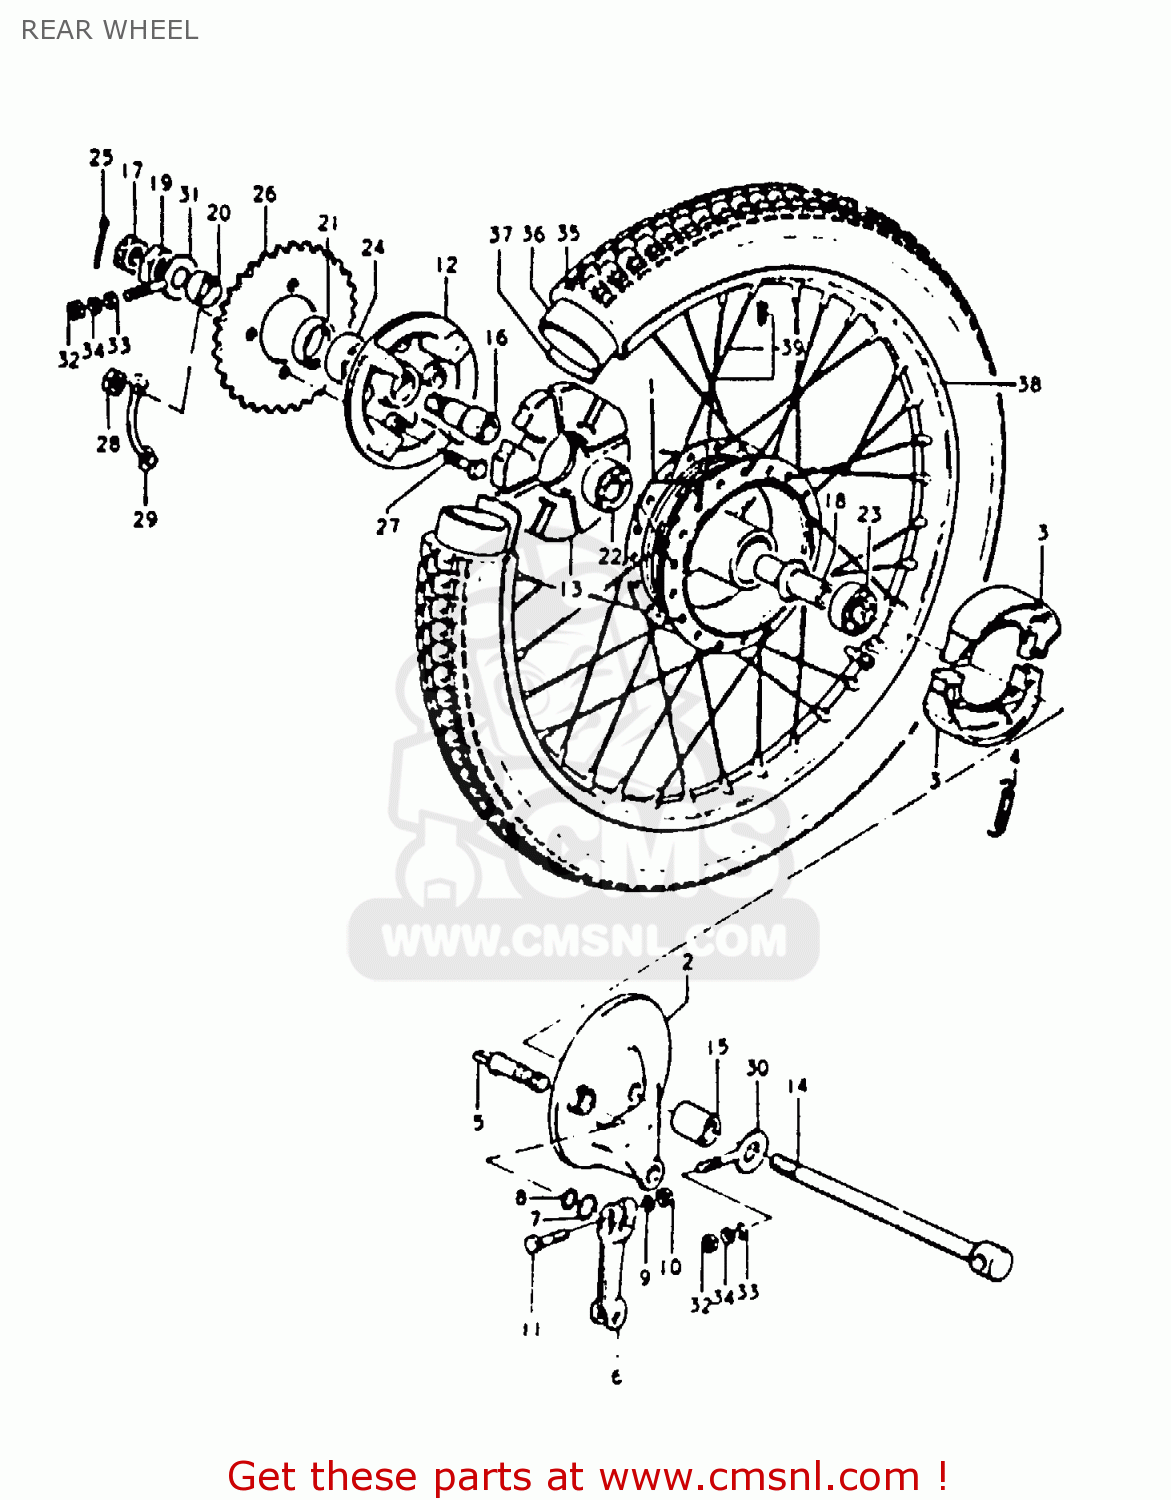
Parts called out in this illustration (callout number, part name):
1	HUB,REAR WHEEL
2	PANEL,REAR HUB
3	SHOE,BRAKE
4	SPRING(L:34)
5	CAM,FR BRAKE
6	LEVER,REAR BRAKE CAM
7	WASHER(12.5X20X1)
8	O RING(D:2.5,ID:11.4)
9	WASHER
10	NUT
11	BOLT
12	DRUM,REAR SPROCKET MOUNT
13	CUSHION,REAR DRUM
14	AXLE,REAR
15	SPACER(12.2X22X30.5)
16	SHAFT,RR SPROCKET DRUM
17	NUT
18	SPACER (12.6X19X58)
19	NUT
20	SPACER(17X25X10.5)
21	SEAL OIL(25X40X6)
22	BEARING
23	BEARING
24	BEARING
25	COTTER PIN
26	SPROCKET,RR
27	BOLT(8X33.5)
28	NUT
29	WASHER
30	ADJUSTER,CHAIN,R
31	PLATE,CHAIN ADJUSTER
32	NUT
33	WASHER
34	LOCK WASHER
35	TIRE, REAR
36	TUBE,INNER
37	PROTECTOR,WHEEL,INNER
38	RIM,WHEEL(1.40X18)
39	SPOKE SET,REAR
